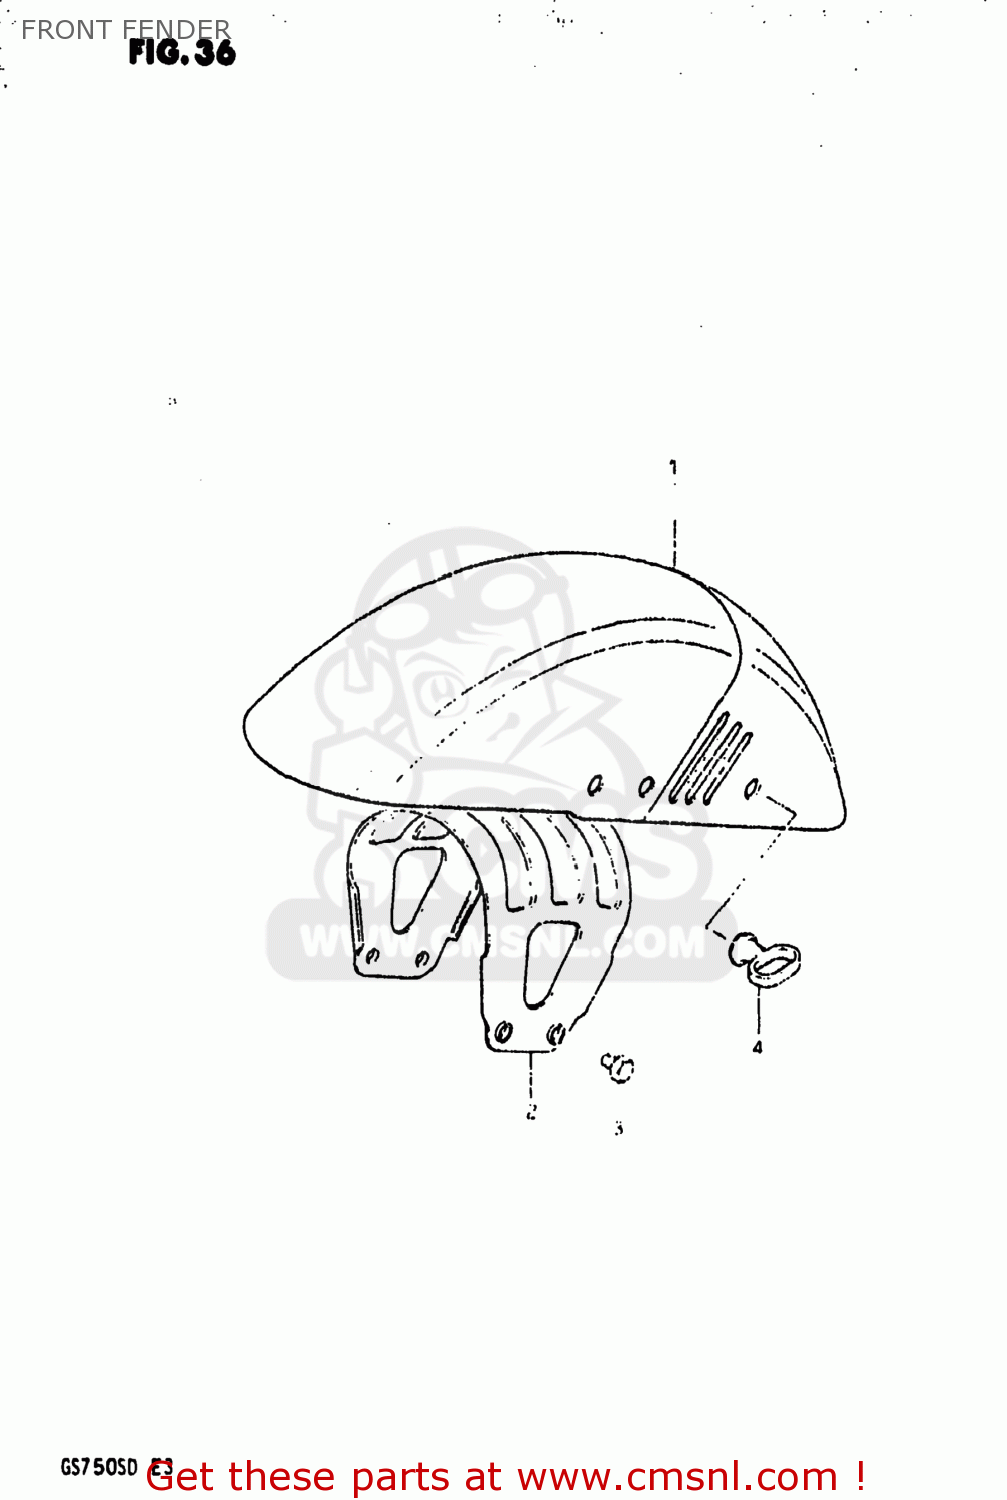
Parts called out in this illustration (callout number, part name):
1	FENDER,FR
2	BRACE,FR FENDER CTR
3	BOLT 8X16
4	GUIDE,CABLE
